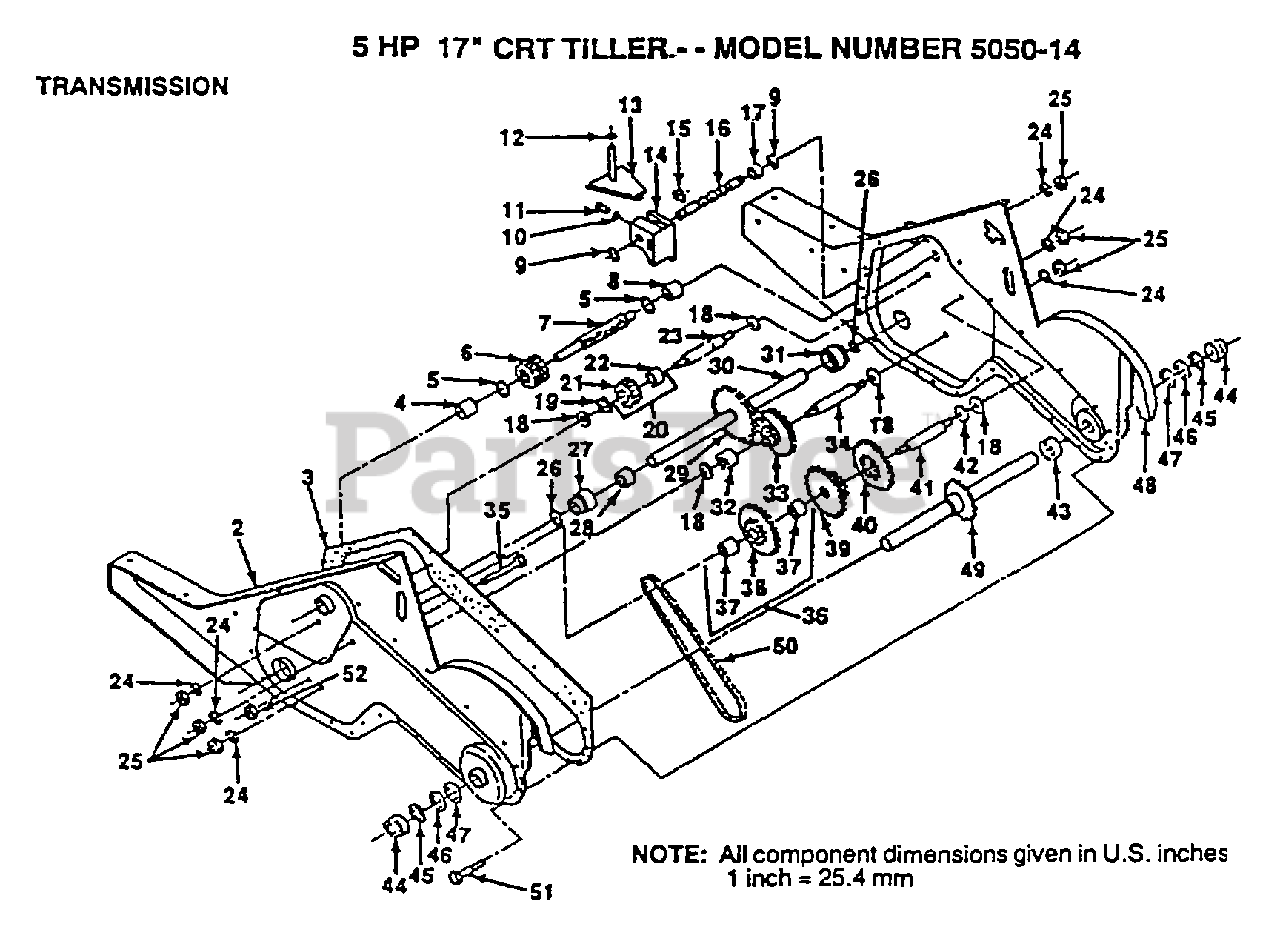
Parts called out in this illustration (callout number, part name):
3	GASKET TI
4	NEEDLE BRNG LT
5	"T, BEARING"
6	PINION-INPUT CRT
7	SHAFT-INPUT CRT
8	"TI, BEARING"
9	WASHER SEAL CRT
11	SPRING-SHIFT CRT
12	O-RING TI
13	ARM ASSY CRT
14	SHIFT FORK TI
15	KLIP RING
16	SHAFT SHIFT CRT
17	SPACER SPLIT CRT
18	WASHER
19	KLIP RING
20	GEAR ASSY CRT
21	GEAR-REV IDLR CRT
22	NEEDLE BEARING TI
23	SHAFT CRT
24	LOCKWASHER
25	NUT.ASF.HEX.7/16
26	O RING CRT
27	"CRT, BEARING"
28	BUSHING TI
29	CHAIN CRT
32	SPACER TI
33	SPRCKT 8 GEAR CRT
34	SHFT 2ND RED. CRT
35	SCRW WHIZ LOK CRT
37	BEARING
39	GEAR TI
40	GEAR TI
41	REDUCTION SHFT TI
42	BRNG RACE
43	SPACER TI
44	CUP.FORMED.
45	RING SPIRAL CRT
49	SHAFT ASSY TI
51	SCREW CRT
52	NUT.HEX.5/16-18
